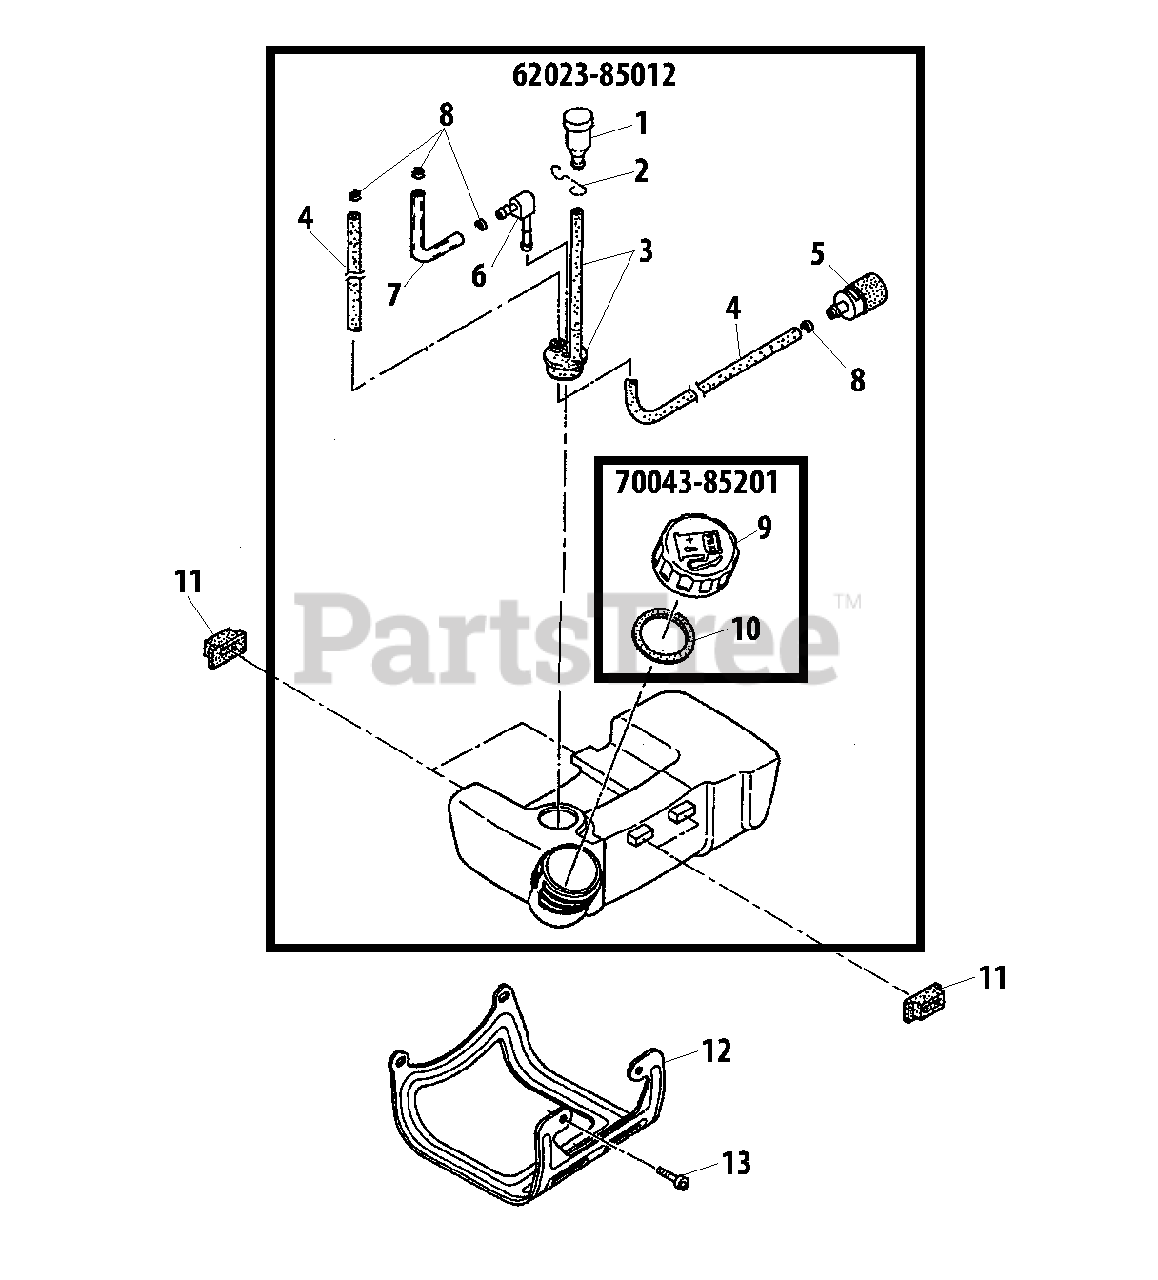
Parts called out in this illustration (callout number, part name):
1	VENT ASSY
2	CLIP, VENT ASSY
3	GROMMET, FUEL W/VENT PIPE
4	PIPE, FUEL
5	FILTER, FUEL 125-528
6	CONNECTOR, PIPE
7	PIPE, FUEL RETURN
8	CLIP Ø6
9	CAP, FUEL
10	GASKET, FUEL CAP
11	CUSHION, FUEL TANK
12	GUARD, METAL FUEL TANK
13	BOLT M5×12
62023-85012	FUEL TANK ASSY
70043-85201	CAP ASSY, FUEL
